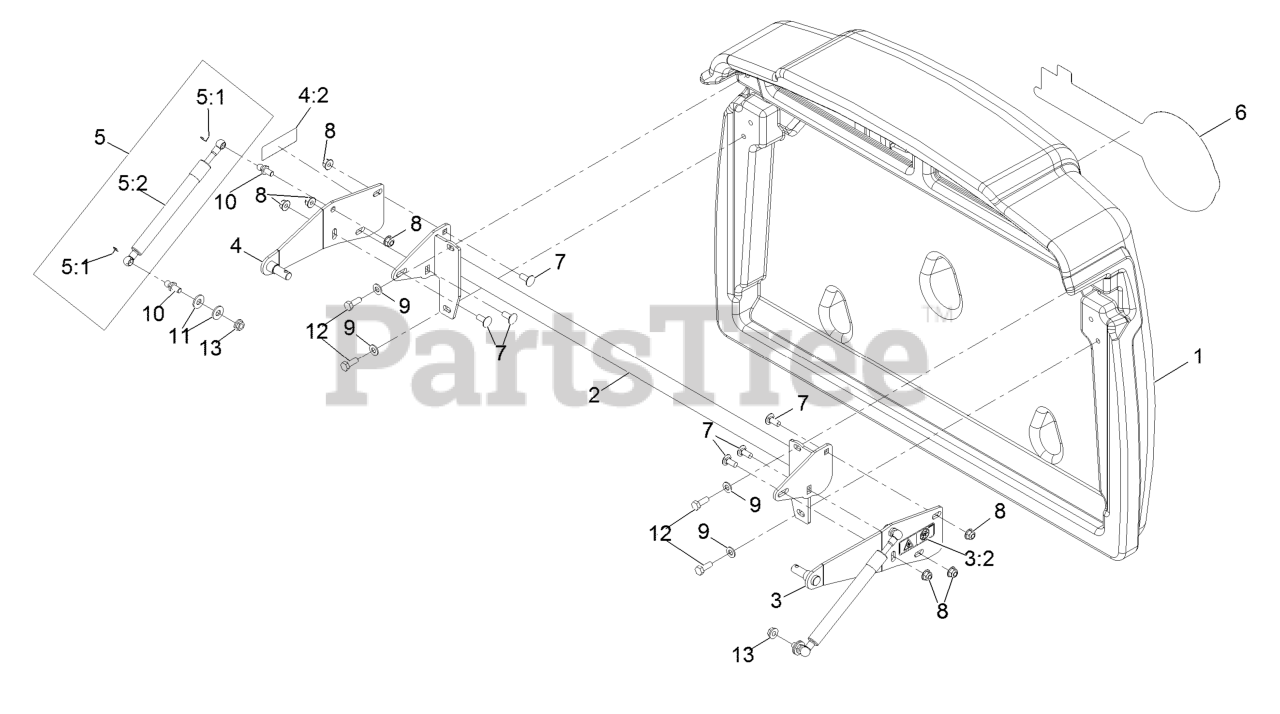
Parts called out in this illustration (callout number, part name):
1	Door, 9.5 Bushel Hopper
2	Support-Door
3	LH Door Pivot ASM
3:2	Decal-Warning, Pinch Point
4	RH Door Pivot ASM
4:2	Decal-Warning, Pinch Point
5	Damper Kit
5:1	Clip-Retainer
5:2	Shock-Gas Tension
6	Decal-Exmark Logo
7	Screw-CARR
8	Nut-HF, NI
9	Washer-Plain
10	Stud-Ball
11	Washer-Flat
12	Screw-HH
